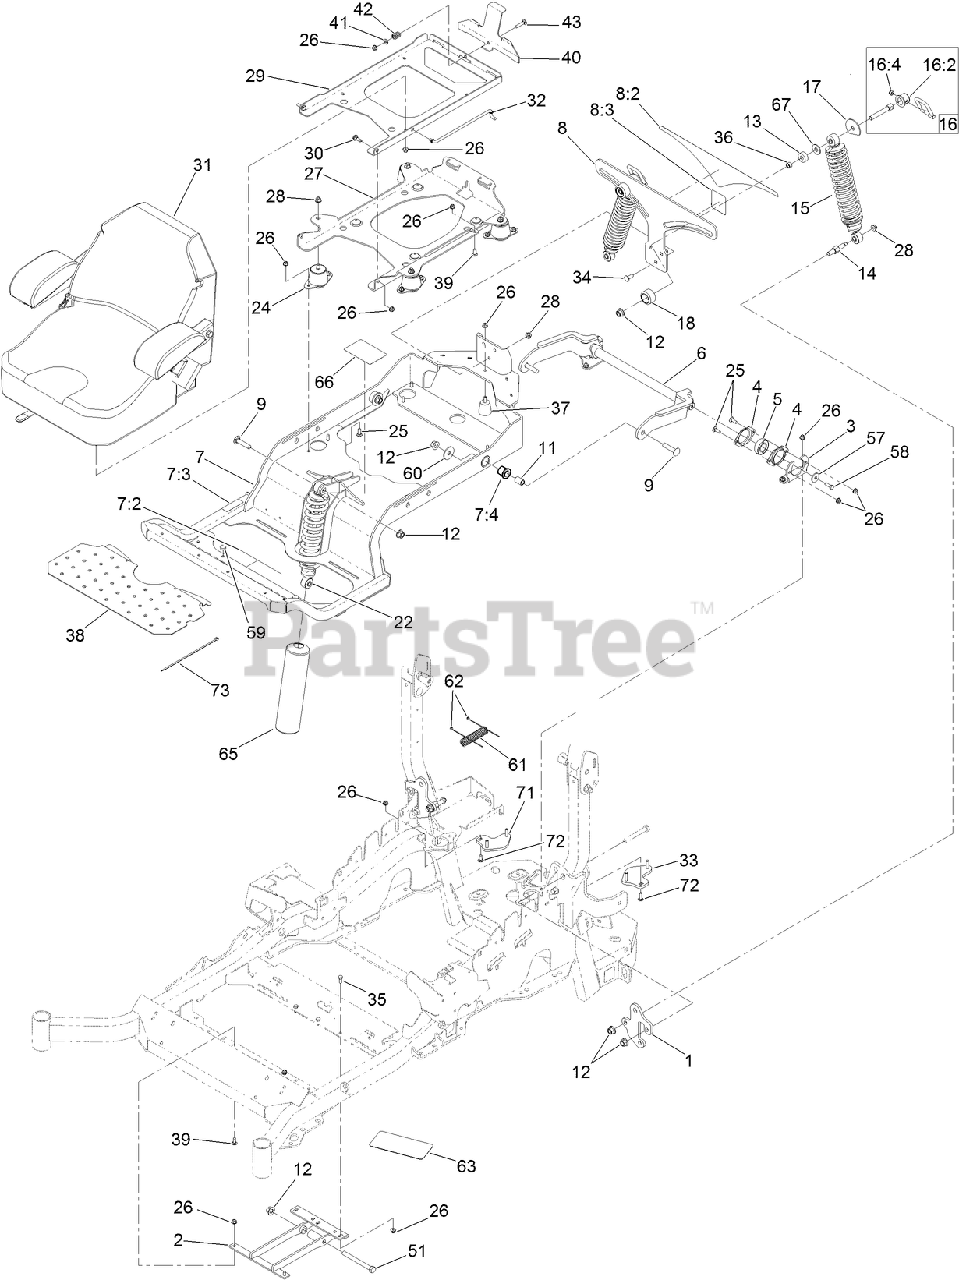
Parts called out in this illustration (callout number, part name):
1	PLATE-MOUNT, SHOCK
2	MOUNT-LOWER
3	BRACKET-BEARING
4	HOUSING-BEARING, FLANGE
5	BEARING
6	ARM-TRAILING
7	SUBFRAME ASM
7:2	DECAL-DANGER
7:3	DECAL-BRAKE, PARKING
7:4	BUSHING-FLANGE
8	BRACKET-MOUNTING
8:2	DECAL-ADJUSTMENT, RIDE
8:3	DECAL-LOCK, CAM
9	SCREW-CARR
11	SPACER-ALUMINUM
12	NUT-LOCK
13	SPACER
14	BOLT-SHOULDER
15	SHOCK-SPRING
16	CAM LOCK ASM
16:2	CAP-LOCK
16:4	NUT-HEX
17	PLATE-STOP
18	KNOB-FRONT
22	SHOCK-SPRING
24	ISOLATOR-SEAT
25	BOLT-CARR
26	NUT-HF, NI
27	PLATE-SUPPORT, ISO SEAT
28	NUT-HF, NI
29	PLATE-FRAME, SEAT
30	SCREW-SHOULDER
31	SEAT-STANDARD
32	ROD-PROP
33	LH PLATE ASM (W/STUDS)
34	SCREW-CARR
35	SCREW-HH
36	BEARING-NEEDLE
37	BUMPER-RUBBER
38	FLOORPAN
39	SCREW-CARR
40	PLATE-LATCH,SEAT
41	WASHER-PLAIN
42	SPRING-COMPRESSION
43	BOLT-CARR
51	SCREW-HH
57	Washer-Flat
58	SCREW-HH, THREAD LOCKING
59	BUMPER
60	WASHER-THRUST
61	COVER-HOSE
62	TIE-CABLE
63	TREAD-GRIP
65	COVER-SHOCK
66	DECAL-SERVICE AID
67	WASHER-FLAT
71	RH PLATE ASM (W/STUDS)
72	SCREW-CARR
73	TIE-PLASTIC
